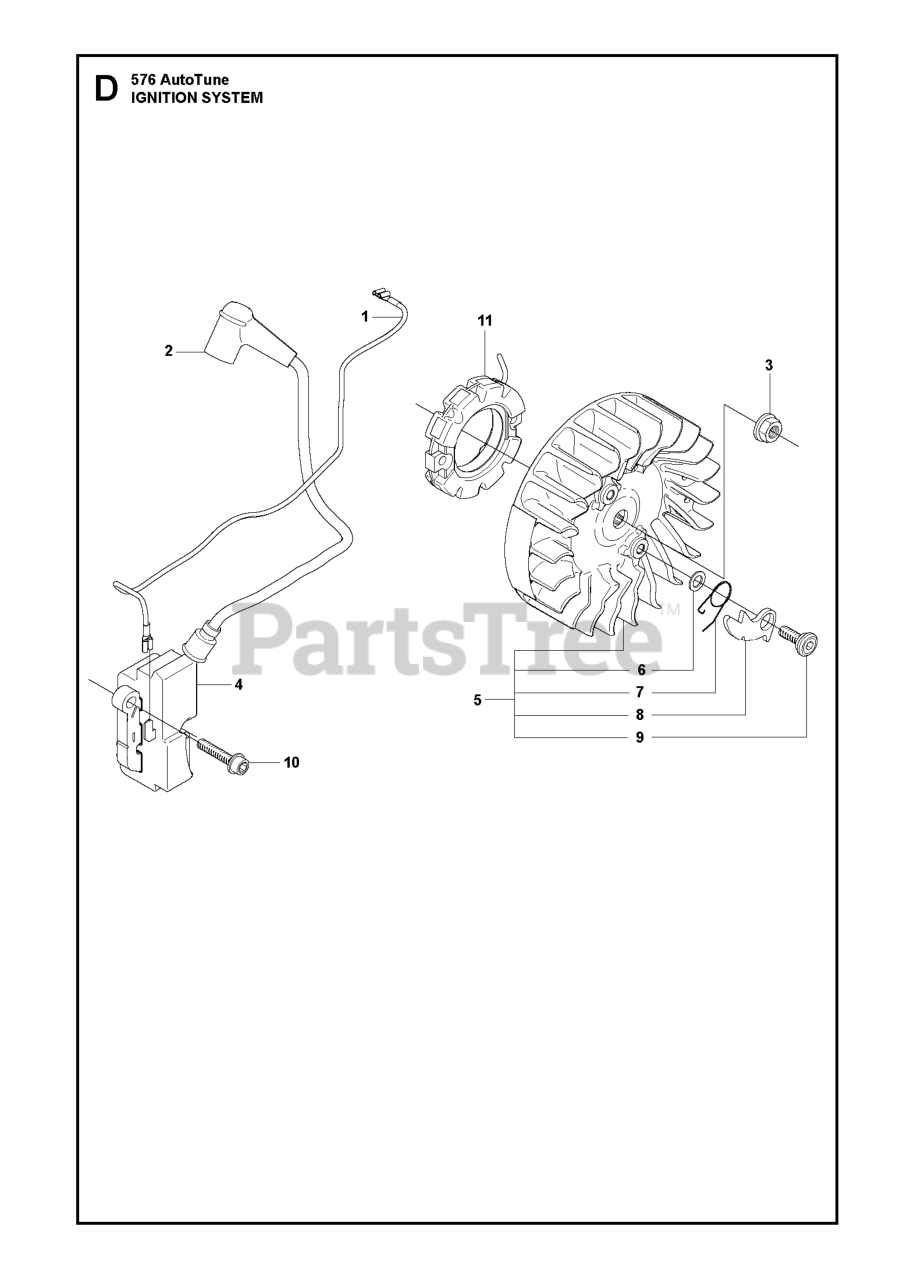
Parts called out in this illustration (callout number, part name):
1	SHORT CIRCUIT CABLE
2	SPARK PLUG CAP
3	NUT W/ WASHER
4	IGNITION MODULE
9	SCREW M5X14
11	STATOR 59MM H576AT
